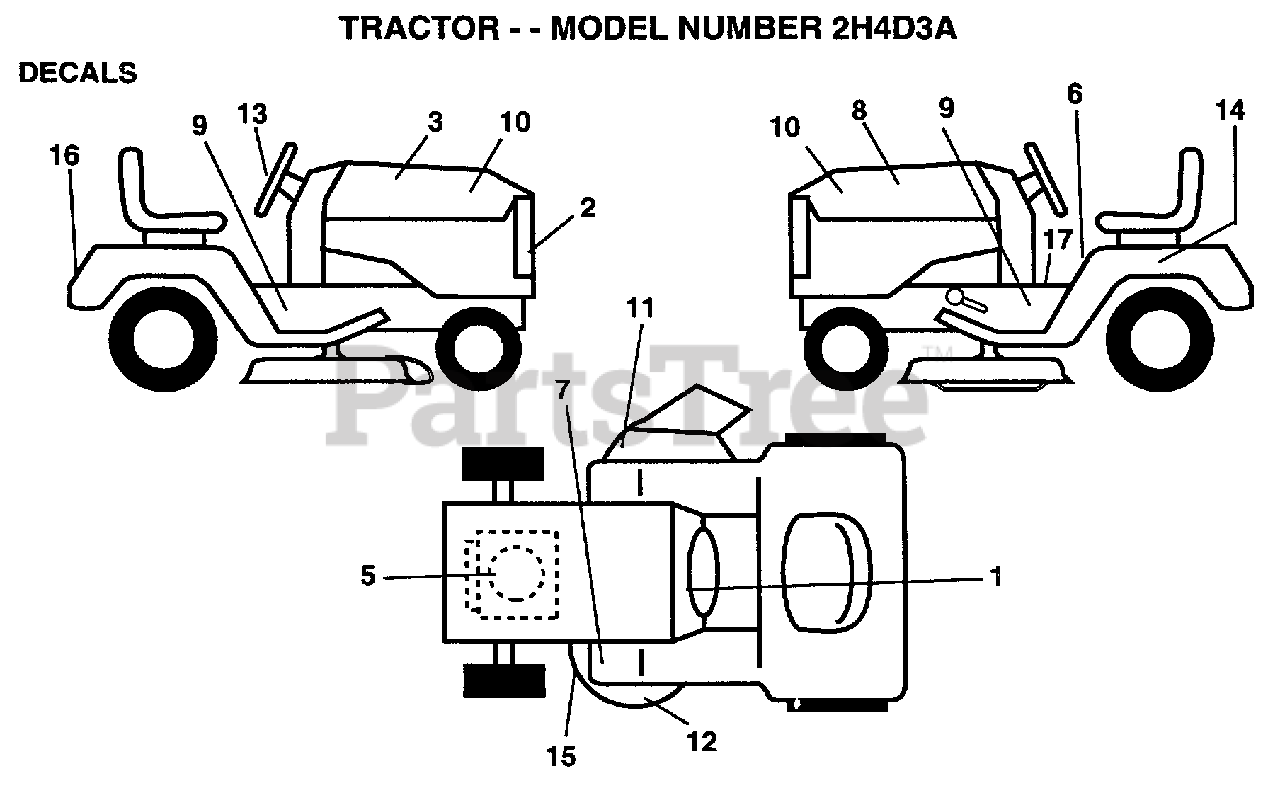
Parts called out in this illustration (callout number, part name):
1	DECAL.DASH.INSTR.
2	GRILL DECAL
3	DECAL.HD.RH.RALLY
5	DECAL.ENG.272632
6	DECAL CAUTION
7	DECAL T
8	DECAL.HD.LH.RALLY
9	CHASSIS DECAL
11	"DECAL, WARNING"
13	"DECAL,STR WHL"
14	DECAL
15	DECAL
16	FENDER DECAL
17	DECAL BRAK PARK
